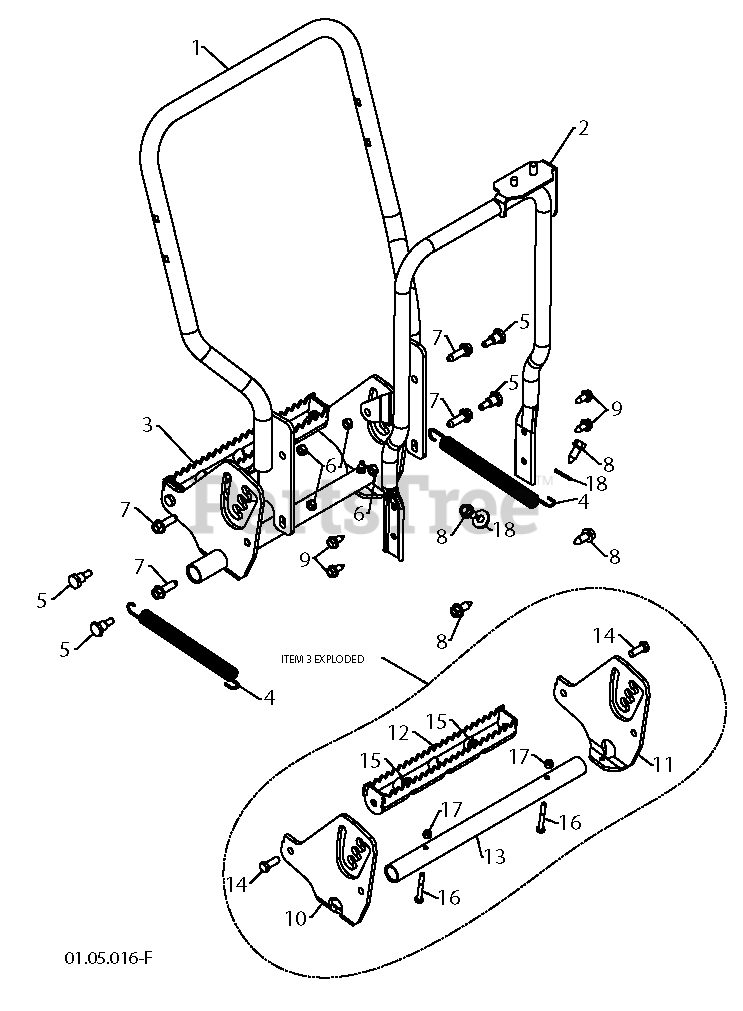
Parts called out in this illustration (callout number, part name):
1	HANDLE.ASM.LOWER.TRACK.GREY
2	SUPPORT.WELDMENT.ROTATOR.BLACK
3	PLATE.FOOT.ASM.SNOW
4	SPRING.EXTENSION.TRACK.SNOW
5	SHOULDERBOLT5/1618
6	NUT.CENTERLOCK.5/16-
7	SCREW.3/8-16
8	SCREW 3/8-16X1
9	BOLT.5/16HEX.WHS.HD
10	FOOT.ADJUST.PLATE.GUIDE.RH.SNO
11	FOOT.ADJUST.PLATE.GUIDE.LH.SNO
12	TRACK.FOOT.ADJ.ASM.SNOW
13	COVER.TRACK.SNOW
15	NUT
16	BOLT.HEX.FINISHED.1/4-20
17	LOCKNUT.NYLOC.1/4-20
18	WASHER,HARDEN
